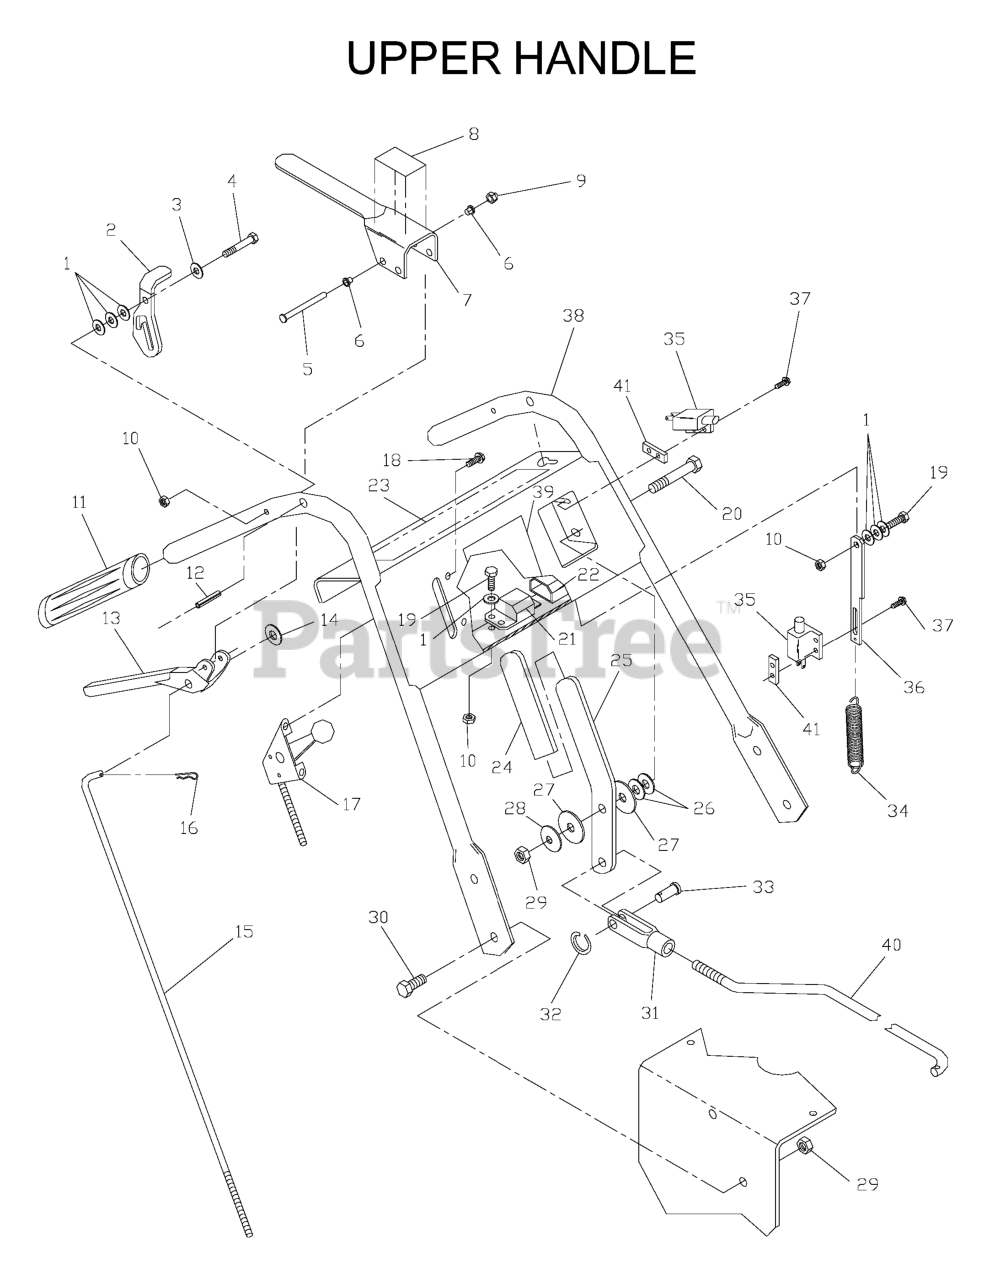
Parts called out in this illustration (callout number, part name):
1	WASHER 1/4 SAE
2	LATCH LT THUMB W/GRIP
3	WASHER, WAVE SPRING
4	BOLT 1/4C X 1 3/4
5	PIN CLEVIS
7	LEVER OPC W/GRIP
8	DECAL, THUMB LATCH
10	NUT 1/4C CENTER LOCK
11	GRIP HANDLE
12	ROLL PIN 5/16 X 1.125
13	LEVER, MOLDED DRIVE
14	WASHER 5/16 FLAT
15	TRACTION ROD
16	HAIRPIN #2
17	THROTTLE CONTROL W/BALL KNOB
18	HWST 1/4C X 3/8
19	HCS 1/4C X 3/4 HCS
20	HCS 3/8C X 1 1/2
22	HANDLE HARNESS
23	DECAL, OPERATING
26	WASHER 3/8 FLAT
27	WASHER, FIBER
28	CONE WASHER
29	NUT 3/8C CENTERBLOCK
30	HCS 3/8-16X1.GRD.5.ZD
31	YOKE-3/8-24 PLTD
33	CLEVIS PIN 3/8 X 1 1/8
36	LINKAGE, O P
37	SCREW #10-24 X 5/8
38	HANDLE, UPPER W/DECALS
39	DECAL, OPERATION
41	TAPPED PLATE
539976388	LATCH, RT.THUMB W/GRIP
